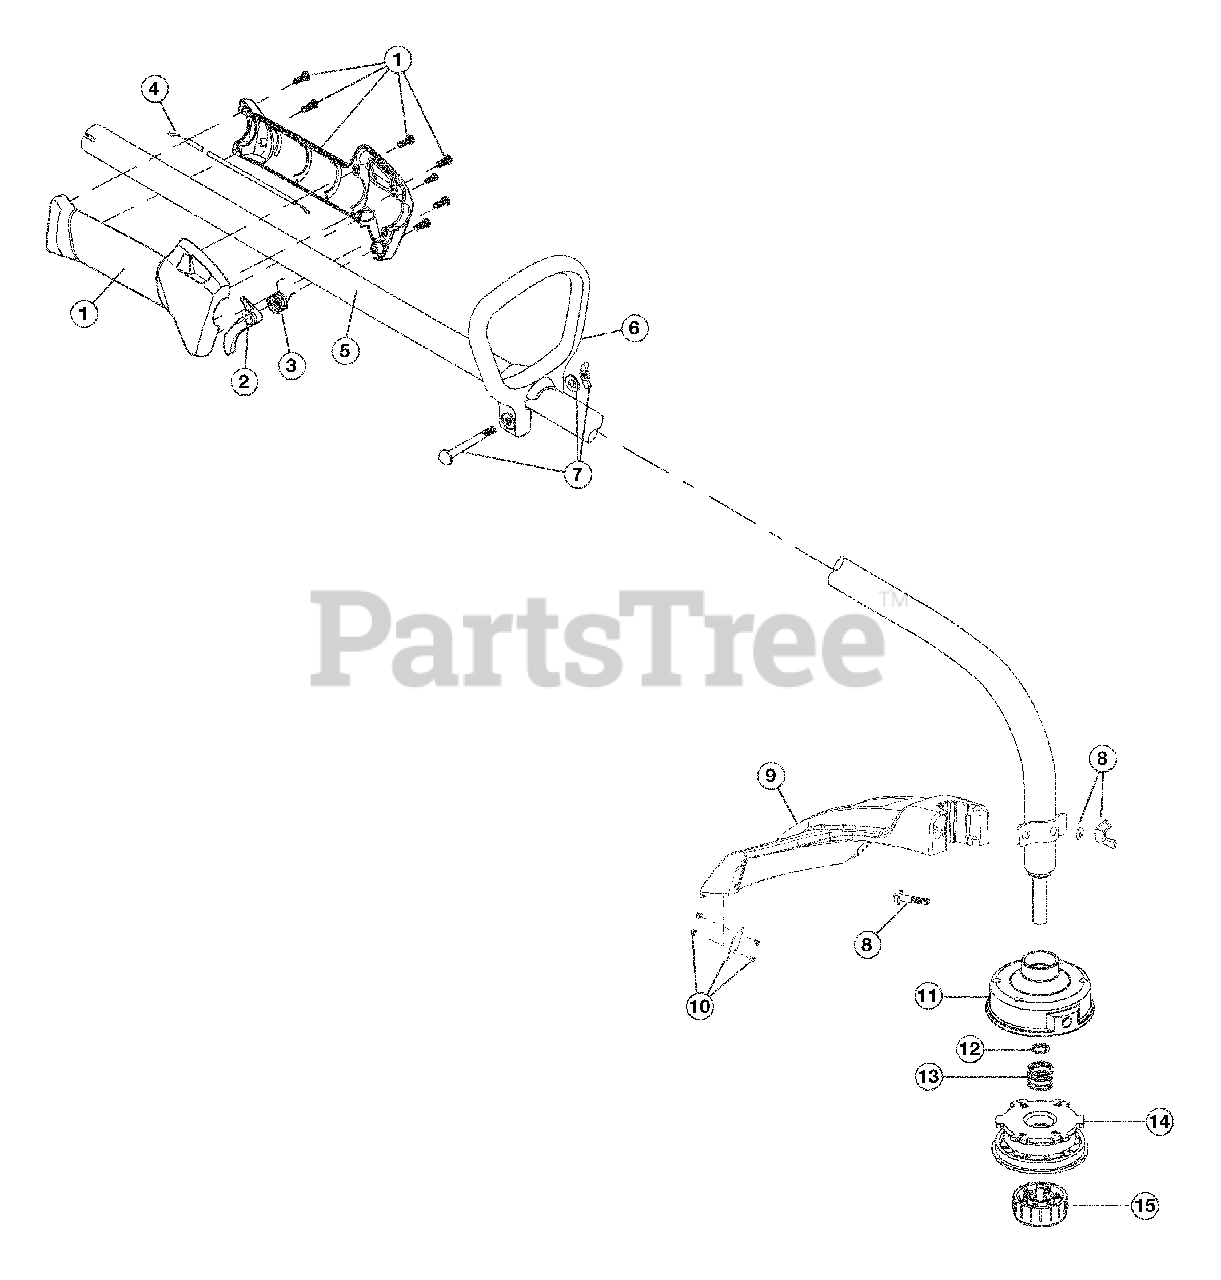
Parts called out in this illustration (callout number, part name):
1	Throttle Housing Assembly
2	Throttle Trigger Spring
3	Throttle Trigger
4	Throttle Cable
5	Drive Shaft Housing Assembly
6	D-Handle
7	Handle Hardware
8	Guard Mounting Hardware
9	Guard
10	Blade Assembly
11	Outer Spool Assembly
12	Retainer
14	Inner Reel
15	Bump Head Knob Assembly
